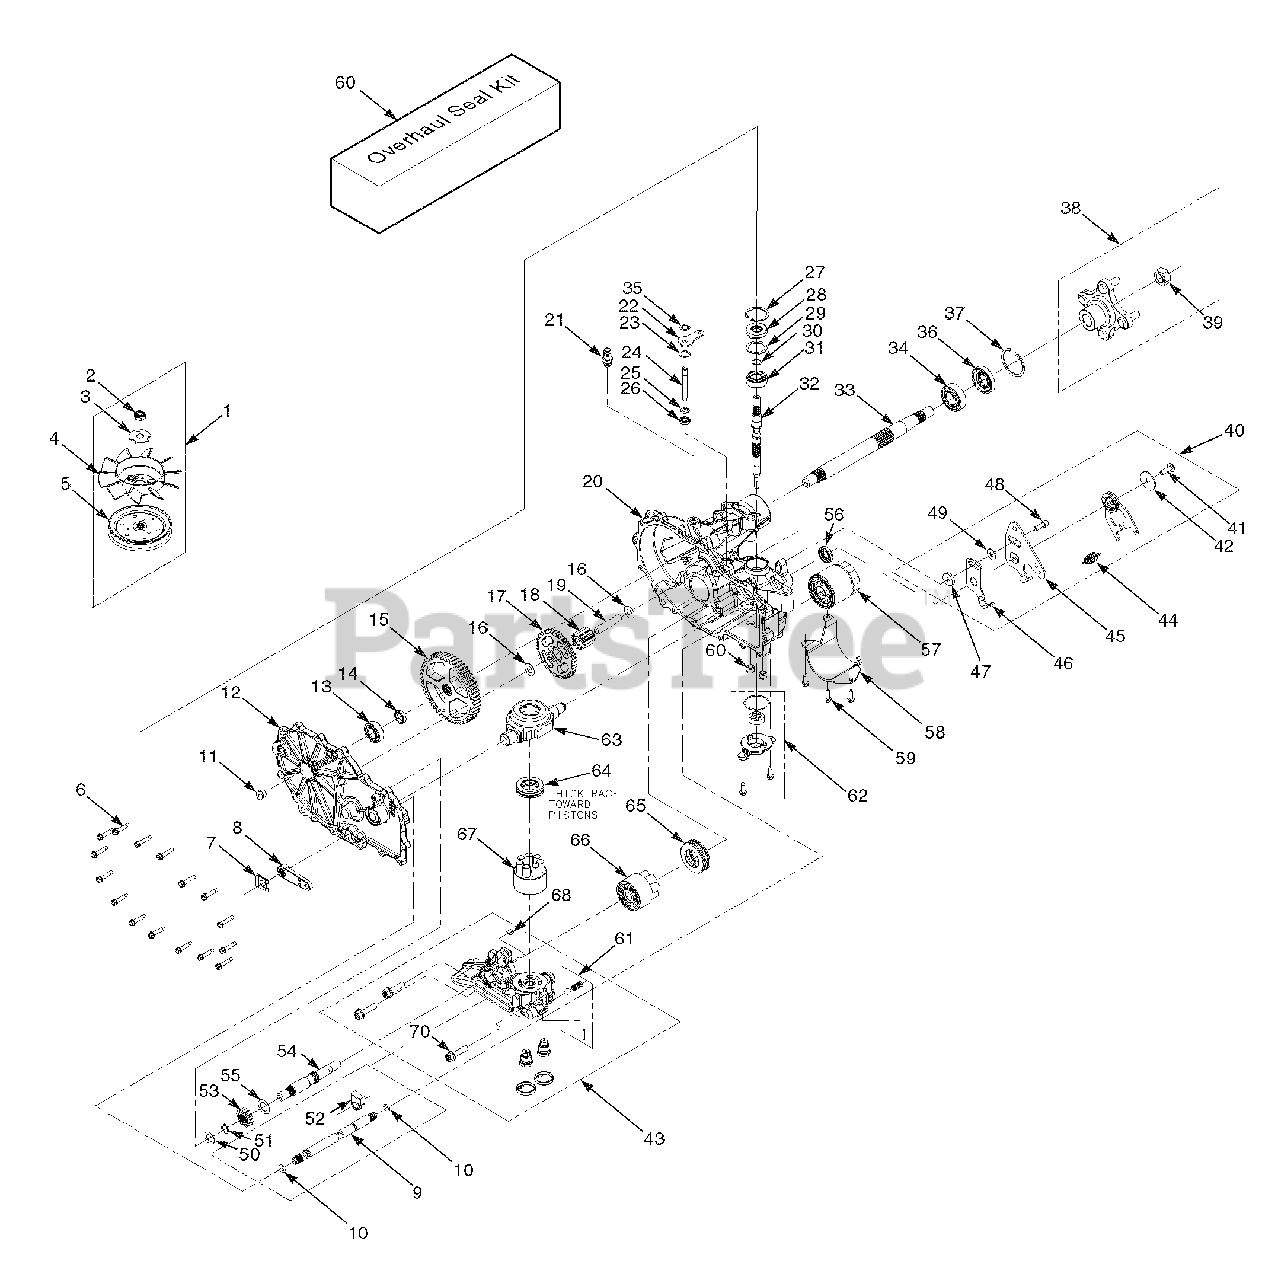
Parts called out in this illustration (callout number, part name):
1	Kit, Fan & Pulley
2	Nut, Hex Locking 1/2-20
3	Washer, Slotted
4	Fan, 7" Dia.
5	Pulley, Cupped 4-1/2" Dia.
6	Bolt, Hex Head 1/4-20 x 1-1/4"
7	Clip, Retaining
8	Handle, Brake
9	Shaft, Brake
10	O-Ring
11	Plug, 9/16-18
12	Kit, Side Cover RH
13	Bearing, Ball .75 x 40 x 12
14	Spacer, .75 x 1.0 x .257
15	Gear, 54T
16	Washer, .5 x 1.0 x .03
17	Gear, 45T
18	Gear, 11T Steel
19	Jackshaft Pin
20	Kit, Housing RH
21	Fitting
22	Arm, Bypass
23	Ring, Retaining .750 Internal
24	Rod, Bypass
25	Ring, Retaining .375 External
26	Seal, Lip .375 x .75 x .25
27	Ring, Retaining 2.06 Internal
28	Seal, Lip 17 x 40 x 7
29	Washer, 1.23 x 1.56 x .04
30	Ring, Retaining Wire
31	Bearing, Ball 17 x 40 x 12 Open
32	Shaft, Input
33	Shaft Kit, Axle
34	Bearing, Ball 1.0 x 52 x 15 Open
35	Ring, Retaining .375 External
36	Seal, Lip 25 x 52 x 10 TC Gray
37	Ring, Retaining 2.06 Internal
38	Kit, Hub
39	Nut, Hex Locking 3/4-16
40	Kit, RTN Assembly
41	Bolt, 5/16-24 x 1" Patch
42	Washer, .343 x 1.5 x .062
43	Kit, Center Section RH
44	Spring
45	Arm, Control
46	Arm, Neutral RH
47	Spacer, .320 x 1.005 x .179
48	Bolt, 5/16-24 x 1" Patch
49	Washer, .34 x .88 x .06
50	Washer, .63 x 1.0 x .05
51	Ring, Retaining
52	Pawl, Brake
53	Gear, 14T Steel
54	Shaft, Motor
55	Washer, .72 x 1.16 x .04
56	Seal, Lip 18 x 32 x 7
57	Filter
58	Filter Guard
59	Bolt, 1/4-20 x 3/4"
60	Seal Kit
61	Kit, Charge Relief
62	Kit, Charge Pump
63	Trunnion Swashplate
64	Thrust Bearing
65	Thrust Bearing
66	Kit, Motor Cylinder Block
67	Kit, Cylinder Block
68	Plate, Bypass
69	Kit, Charge Relief
70	Bolt, Hex Head 3/8-16 x 1-1/2" Patch
